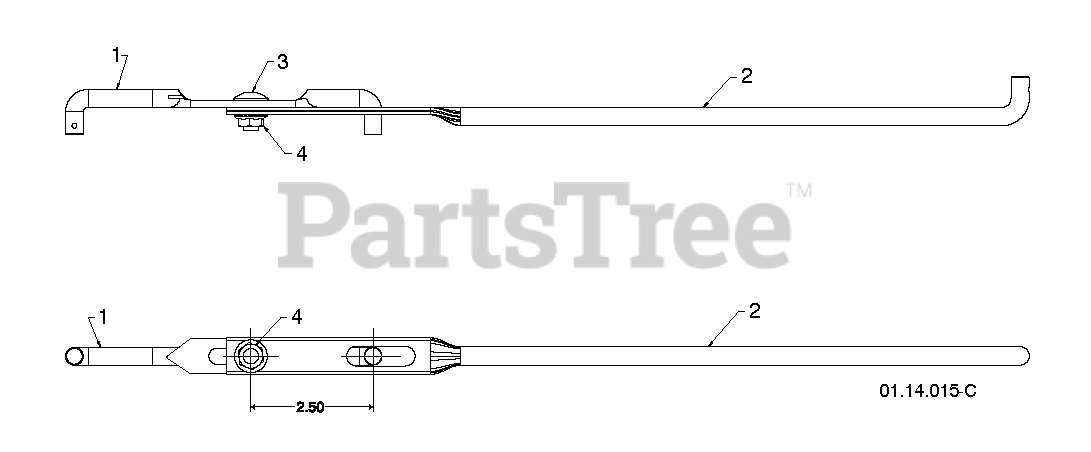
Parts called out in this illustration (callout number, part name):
1	ROD.SHIFTER.TOP.HYD
2	ROD, LOWER, SPEED CONTROL
3	BOLT
4	NUT.FLANGE.5/16
